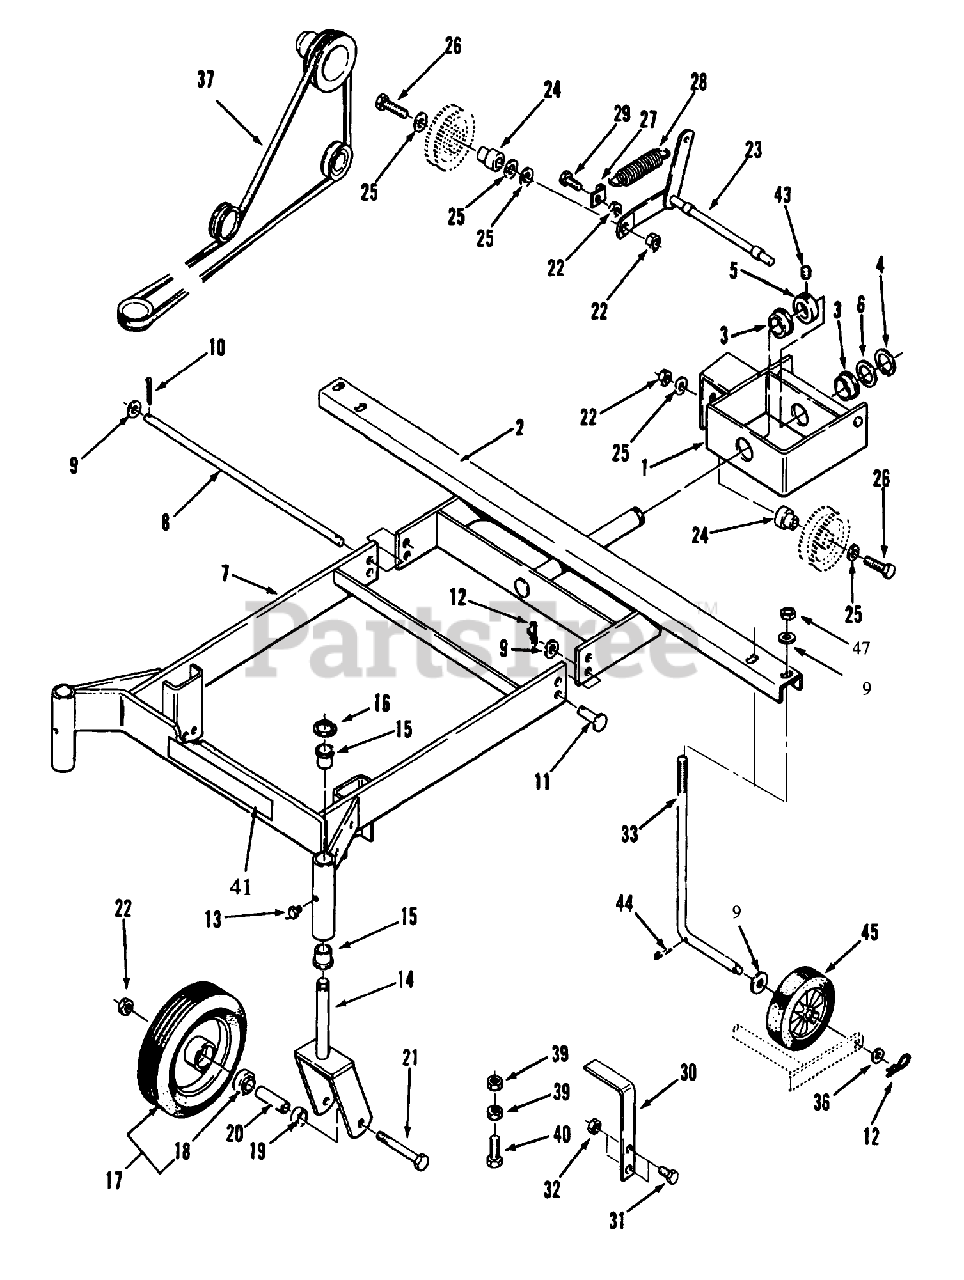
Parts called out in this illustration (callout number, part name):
2	ASSY PIVOT FRAME *R
3	BUSHING
4	RING-RETAINING
6	WASHER
7	ASSY FRAME *R
9	WASHER-FLAT
10	PIN-COTTER
11	CLEVIS PIN
12	Hairpin Cotter
13	FITTING-GREASE
15	BUSHING
16	RING-SNAP
19	SPACER
20	SPACER
21	SCREW-HH
24	SPACER
25	WASHER-FLAT
26	SCREW-HH
27	CLIP - SPRING
28	SPRING-EXTENSION
29	SCREW-HH
30	HANDLE-EXTENSION *R
31	SCREW-HH
33	ROD HANGER *R
36	WASHER-FLAT
39	NUT-HEX, JAM
40	SCREW-HH
41	DECAL - REAR FRAME
44	PIN-COTTER
45	WHEEL ASM
47	NUT-LOCK, NI
